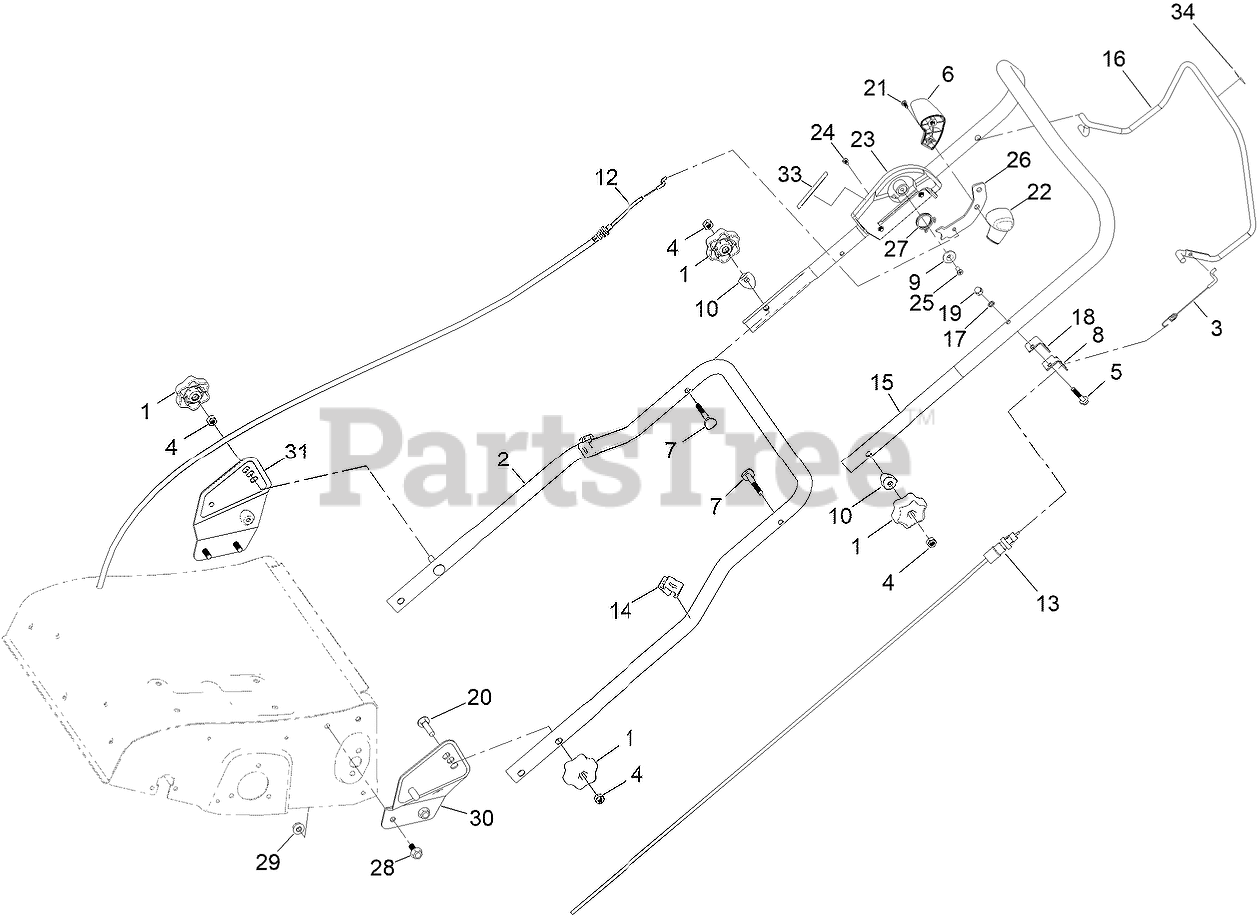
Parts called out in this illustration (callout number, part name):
1	KNOB-HANDLE
2	BAR-HANDLE, LOWER
3	CABLE- LEVER, ENGINE BRAKE
5	SCREW-HHF
6	LEVER HANDLE SECTION
7	BOLT-FLAT HEAD
8	BRACKET-L
9	WASHER-LEVER
10	WASHER-CURVE
12	CABLE-LEVER, TINE RAISE
13	CABLE-LEVER, ENGINE BRAKE
14	CLAMP-CABLE
15	BAR-HANDLE, UPPER
16	LEVER-BRAKE, ENGINE
17	WASHER-LOCK, SPRING
18	BRACKET-L, BRAKE LEVER CABLE
19	NUT-CAP HEAD
20	BOLT-SQUARE CUP HEAD
21	SCREW-PAN HEAD
22	HANDLE-PLASTIC, LEVER RAISE TINE
23	TINE RAISE LEVER BRACKET ASSY
24	SCREW-PAN HEAD
25	SCREW-HEAD, COUNTERSUNK
26	PLATE-ARM, LEVER
27	SPRING
28	BOLT-FLANGE, HEX
29	NUT-FLANGE, HEX
30	LOWER HANDLE BRACKET PLATE LHS
31	LOWER HANDLE BRACKET PLATE RHS
33	DECAL -TRANSPORT LEVER
34	DECAL - STOP
